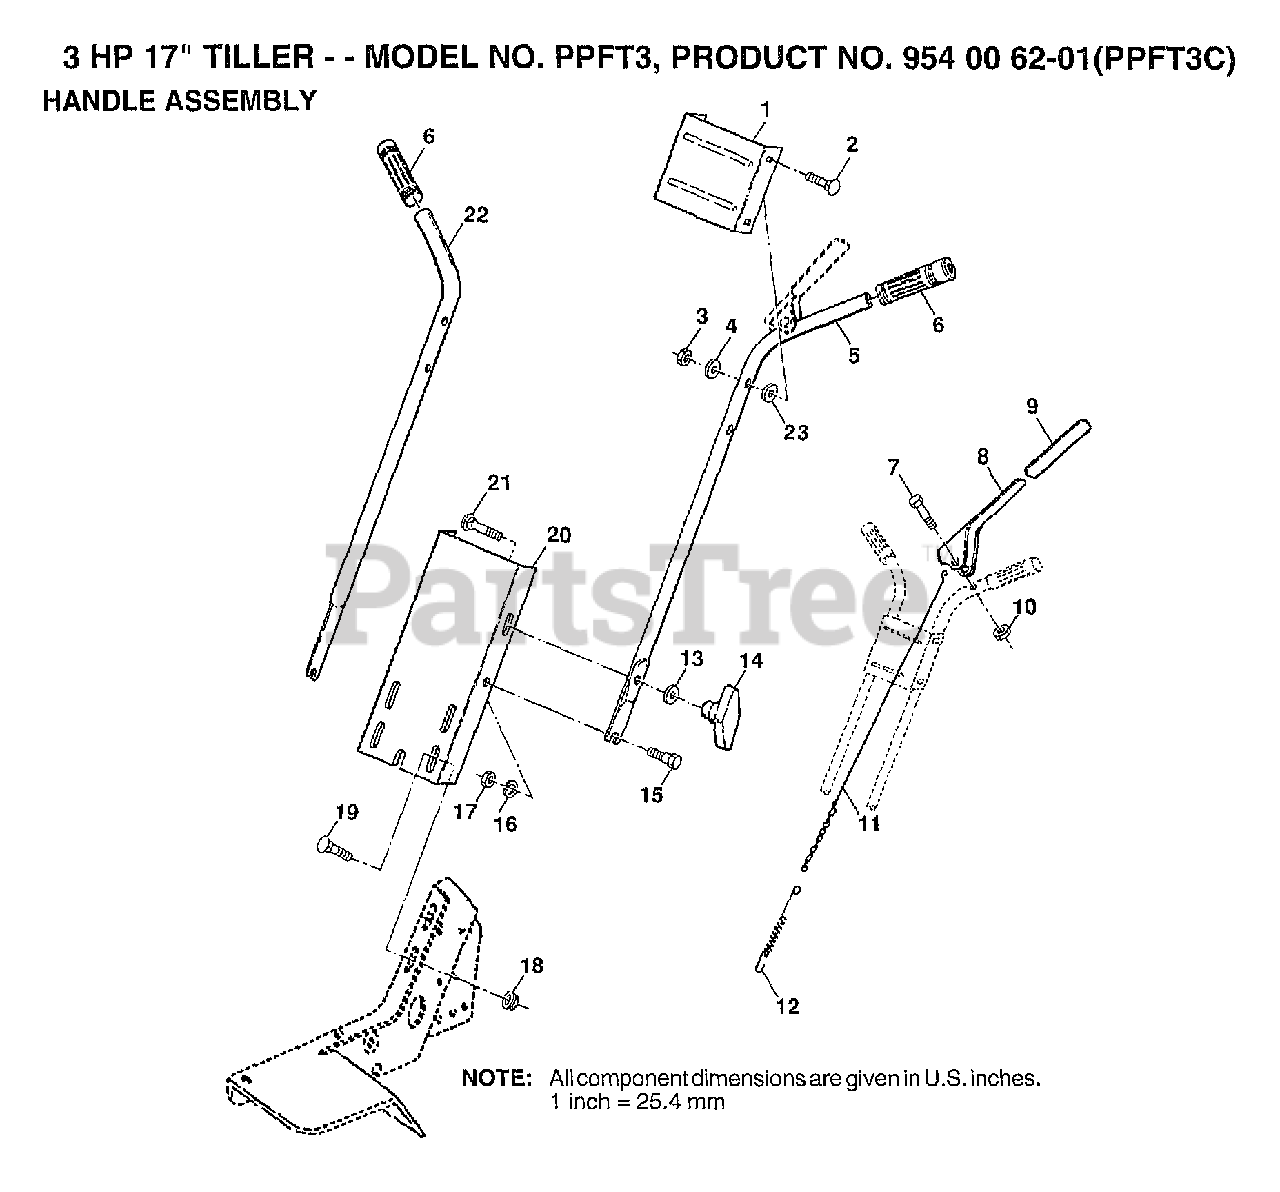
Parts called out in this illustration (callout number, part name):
2	BOLT, CARRIAGE
3	LOCKNUT, CROWN 5/16-18
4	WASHER 11/32 X 11/16 X 16 GA.
7	BOLT, HEX 5/16-18 X 1-1/2
13	WASHER 3/8 X 7/8 X 14 GA.
18	NUT, FLANGED
19	BOLT, CARRIAGE
23	WASHER
